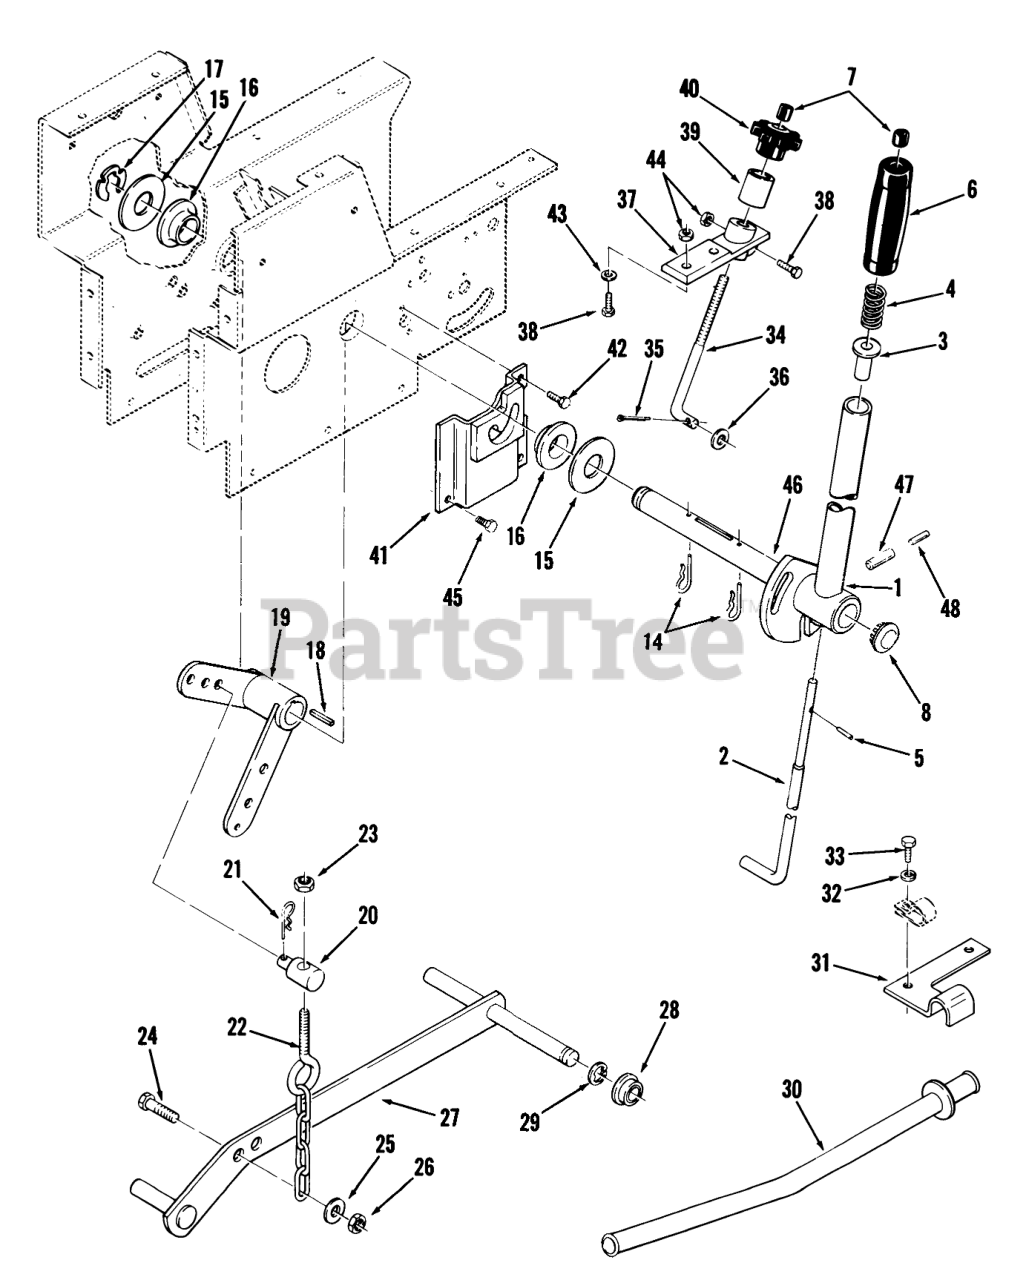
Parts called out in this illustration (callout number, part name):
1	Lift Lever
2	ROD-LATCH LIFT
3	RETAINER-SPRING
4	SPRING-COMPRESSION
5	PIN-SPIROL
6	HANDGRIP
7	CAP-ROD, PLUNGER
8	PLUG
14	Pin-Cotter
15	WASHER
16	BEARING-FLANGE
17	Retainer
18	KEY-SQUARE
19	Bellcrank
20	TRUNNION-LIFT
21	Hairpin
22	CHAIN-LIFT
23	Nut
24	Bolt
25	WASHER 5/16 SAE
26	Nut
27	ASSY LIFT BAR R
28	BUSHING
29	E Ring
30	TUBE ASSY COMPLET R
31	CLAMP-CONDUIT R
32	LOCKWASHER
33	Bolt
34	Rod
35	Pop Rivet
36	WASHER -4
37	Casting
38	Bolt
39	Sleeve
40	KNOB-LIFT CONTROL
41	Latch Bracket
42	SCREW
43	WASHER 5/16 SAE
44	Nut
45	Bolt
46	SHAFT-LIFT LEVER
47	SPIROL PIN
48	Roll Pin
